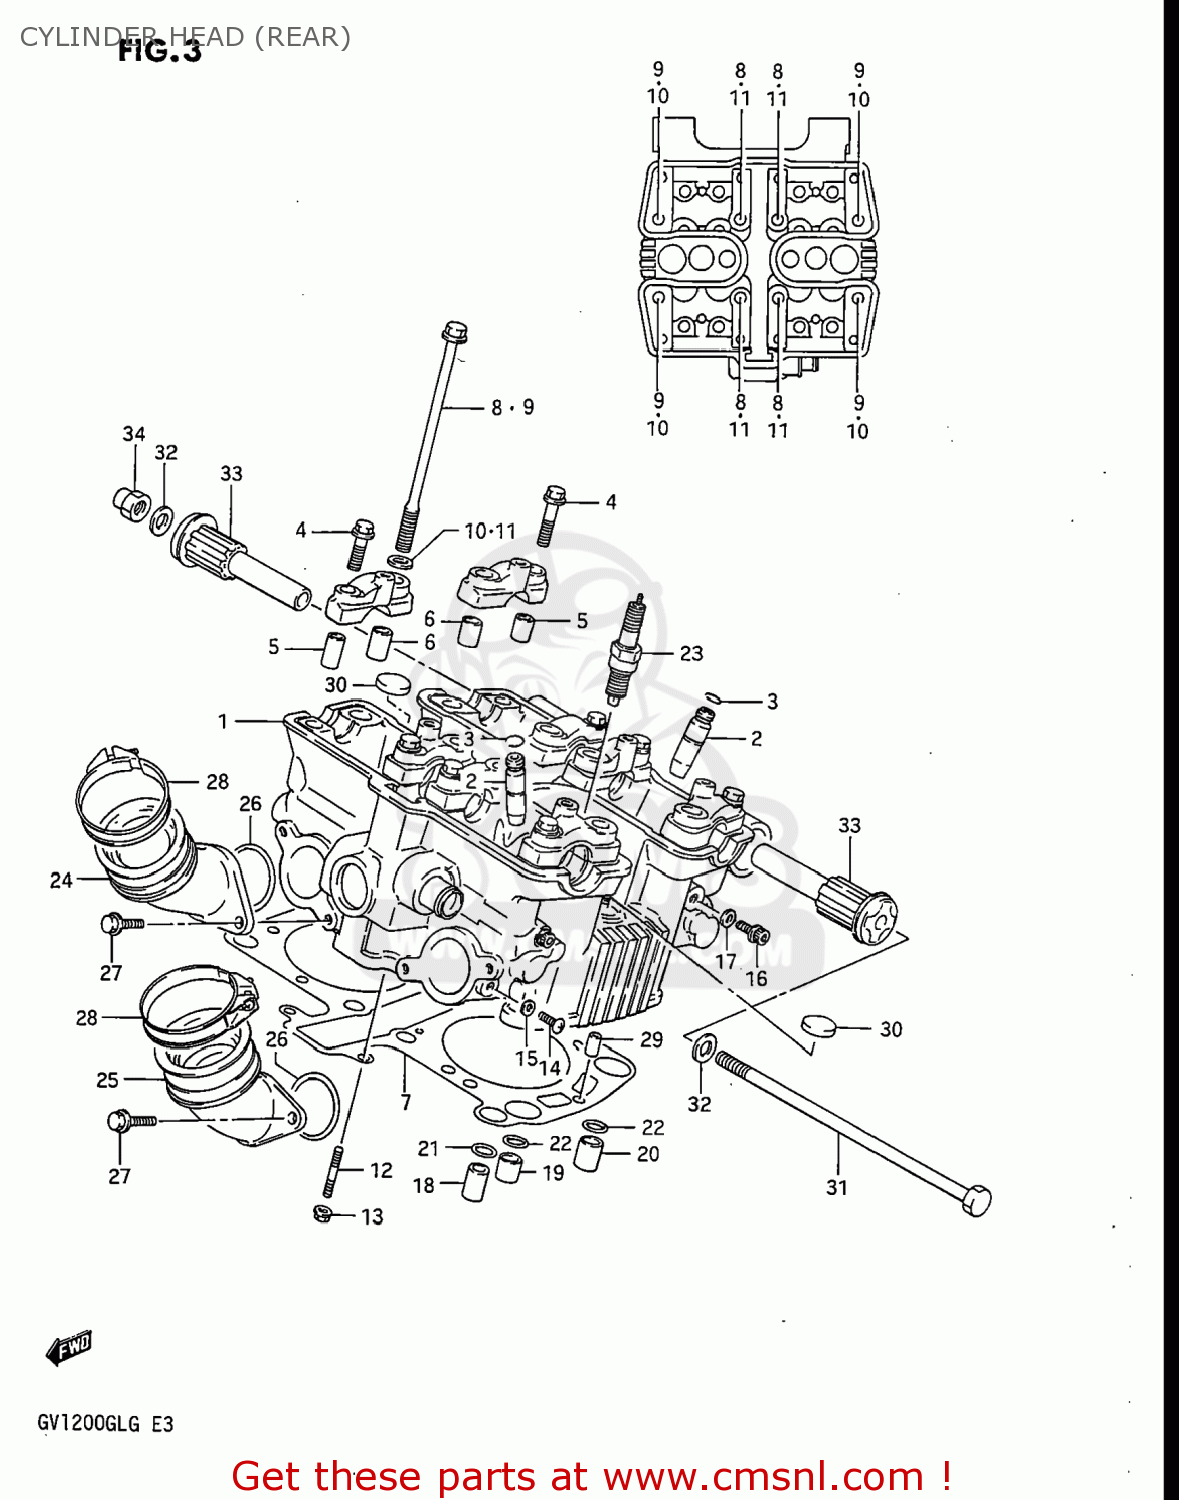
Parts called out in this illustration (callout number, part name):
1	HEAD,CYLINDER,REAR
2	GUIDE,VALVE
3	RING,SNAP
4	BOLT
5	PIN (11X20)(SUS)
6	PIN(10.4X13X22)
7	GASKET,CYLINDER HEAD,REAR (MCA)
8	BOLT
9	BOLT
10	WASHER
11	WASHER (10X20X2.3)
12	STUD 6X25
13	NUT 6MM
14	SCREW
15	GASKET(5.3X9.3X1.2) (NAS)
16	BOLT
17	GASKET(6.2X13X1.2) (NAS)
18	PIN(6.4X9X20)
19	PIN
20	PIN
21	O RING(D:1.9,ID:8.6)
22	O RING(D:1.9,ID:12.6)
23	SPARK PLUG D8EA
24	NET,INTAKE
25	PIPE,INTAKE
26	O-RING (D:2.4 ID:39.7)
27	BOLT
28	CLAMP,PIPE
29	PIN
30	PLUG
31	BOLT
32	WASHER
33	BUSHING,ENGINE MOUNT
34	NUT
